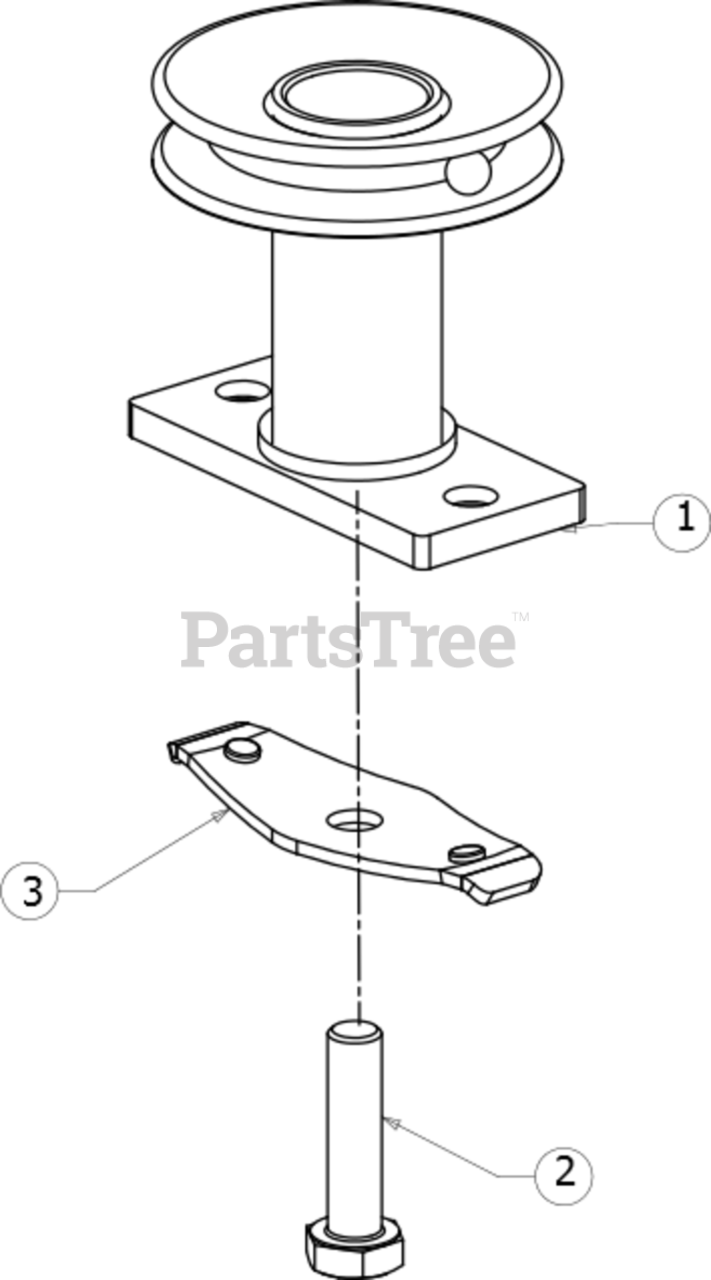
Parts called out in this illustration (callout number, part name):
1	DRIVE PULLEY
2	SCREW 3/8-24 X 1.50 GR8
3	BLADE BELL SUPPORT
